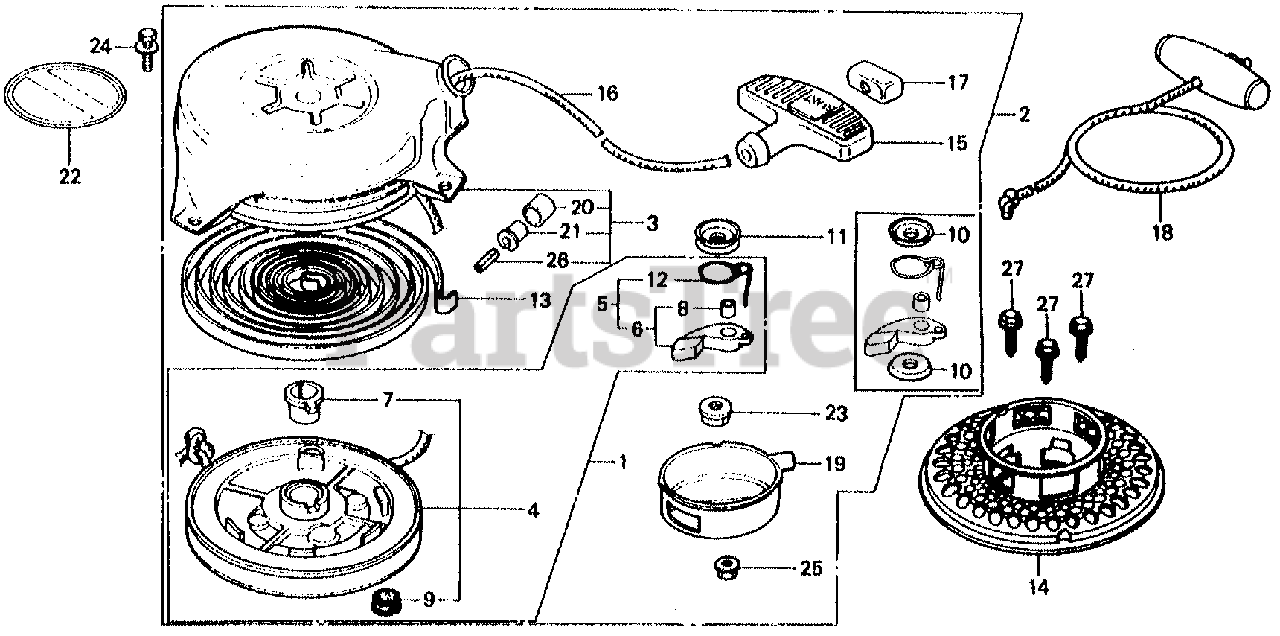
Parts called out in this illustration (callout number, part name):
1	REEL, STARTER
2	STARTER ASSY., RECOIL *NH67* (SPARKLE WHITE)
3	CASE, STARTER *NH67* (Honda Code 1044809). (SPARKLE WHITE)
4	REEL, STARTER
5	RATCHET KIT
6	RATCHET
7	BOSS, REEL
8	BUSH, RATCHET
9	BUSH, REEL STARTER
10	PLATE, FRICTION
11	PLATE, FRICTION
12	SPRING, FRICTION
13	SPRING, RETURN
14	PULLEY, STARTER
15	GRIP, STARTER
16	ROPE, STARTER (#5X55")
17	SUPPORT, GRIP
18	ROPE, STARTER (#5X55")
19	COVER, REEL STARTER
20	ROLLER, GUIDE
21	BUSH, ROLLER
22	EMBLEM
23	NUT, SELF-LOCK (8MM)
24	BOLT, FLANGE (6X8)
25	NUT, FLANGE (5MM)
26	PIN, SPRING (3X18)
27	BOLT, FLANGE (6X16)
